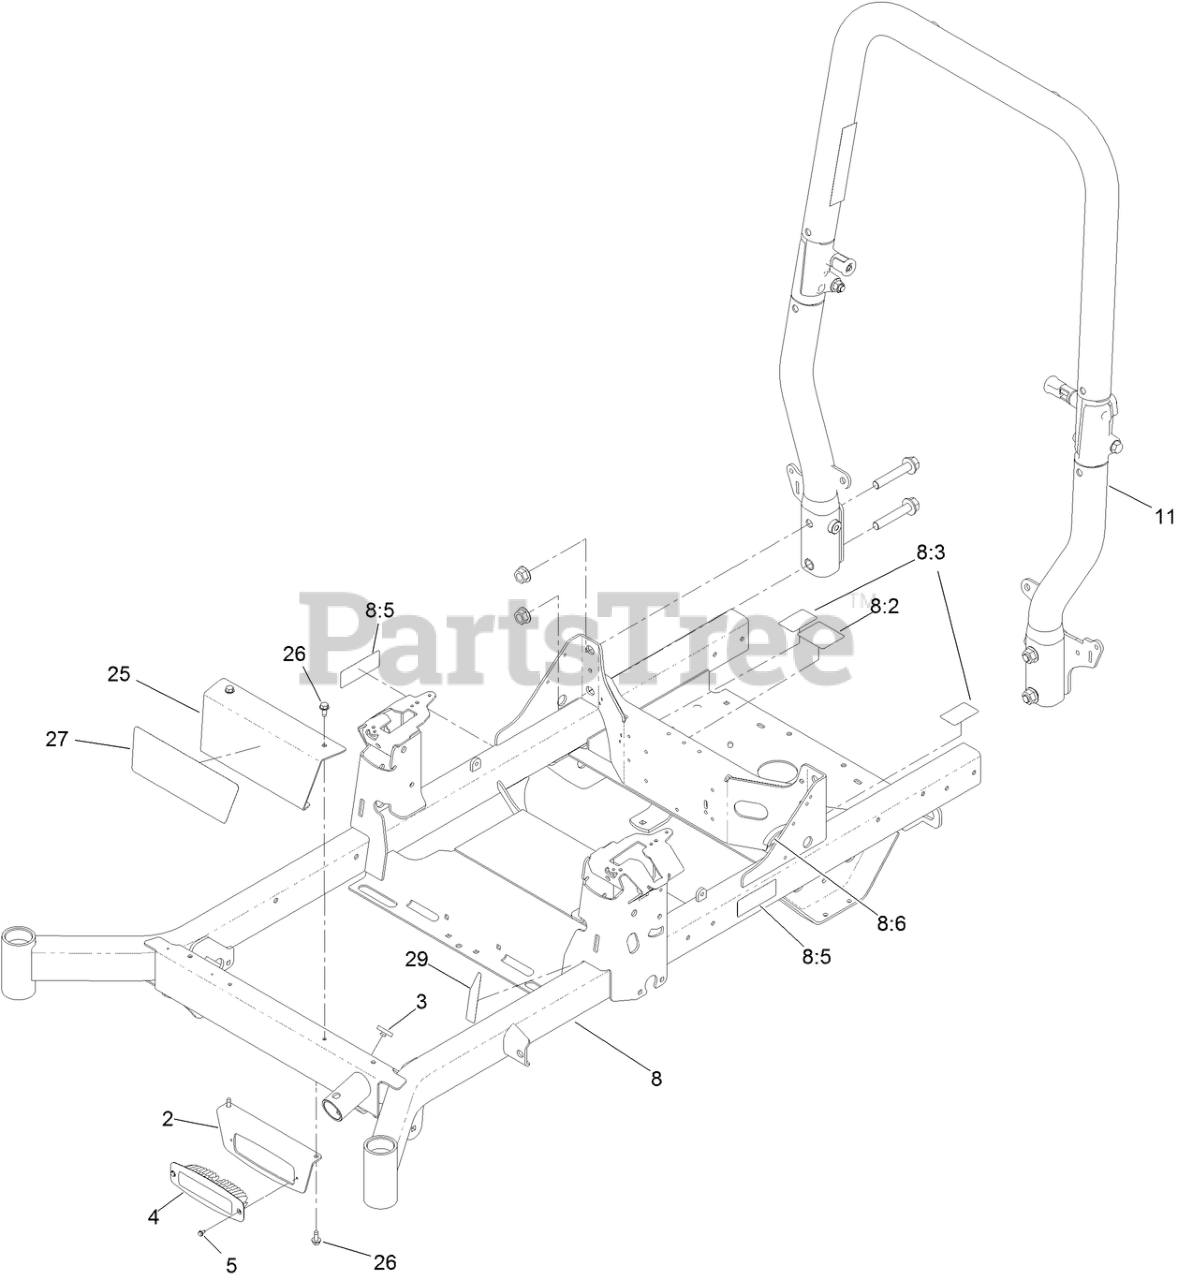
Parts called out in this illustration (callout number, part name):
2	BRACKET-LIGHT
3	BUMPER-PUSH-IN, RUBBER
4	MOUNT-FLUSH, LIGHT
5	SCREW-HWH
8	FRAME-60, SUSPENSION
8:2	DECAL-ROUTING, BELT
8:3	DECAL-RELEASE, DRIVE
8:5	DECAL-WARNING
8:6	STRIP-SEAL
11	ROPS ASM
25	PLATE-FRONT
26	SCREW-HWHTF
27	DECAL-Z MASTER
29	DECAL-FILL, FUEL
